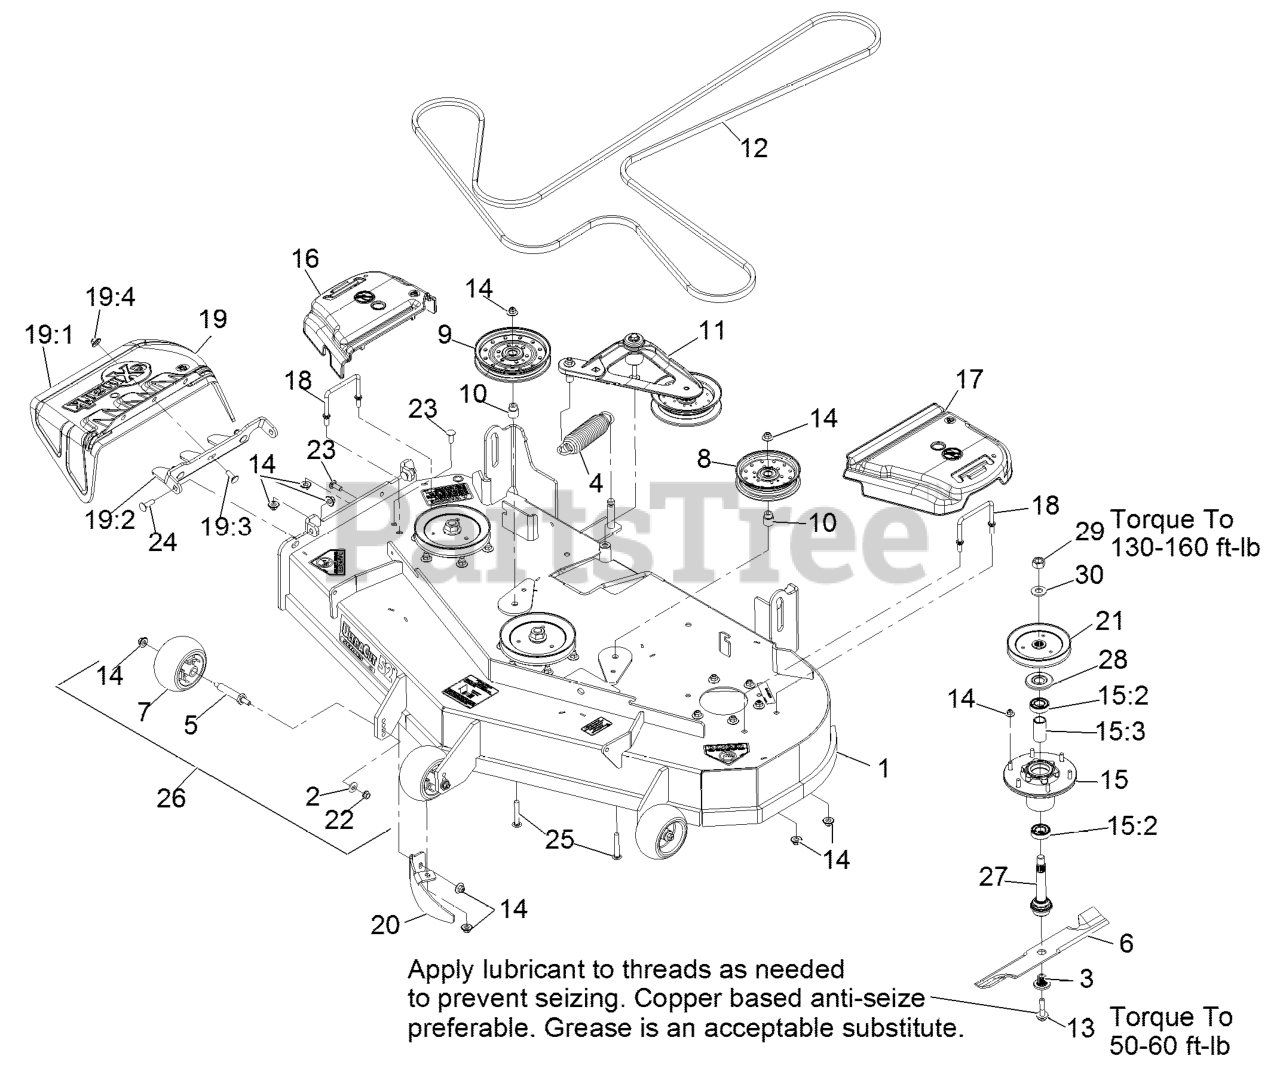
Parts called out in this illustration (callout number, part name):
1	ASM,524 DECK WITH DECALS
2	WASHER-BELLEVILLE
3	BUSHING,SPLINED
4	SPRING-EXTENSION
7	ROLLER-SCALP, ANTI
10	BUSHING-IDLER
11	DECK IDLER ASM
13	SCREW,SEMS 1/2-20 X 2.19
14	Nut-Nyloc 3/8-16 Flg
15	ASM-CUTTER HSG WITH BEARINGS
15:2	BEARING-BALL
15:3	SPACER-BEARING
16	COVER-BELT, RH
17	COVER-BELT, LH
18	WIREFORM-COVER
19	ASM,DISCHARGE CHUTE
19:1	CHUTE,DISCHARGE
19:2	BRACKET,DISCHARGE CHUTE
19:3	SCREW-CARR
19:4	Nut-Nyloc 3/8-16 Flg
20	BAFFLE-DOGLEG, LZE-PNS-52
21	SHEAVE,BLADE DRIVE 6.50
22	NUT-HHF, WHIZ
23	SCREW-CARR
24	Bolt-Carriage 3/8-16 X 1 1/4
25	SCREW-CARR
27	ASM-SPINDLE AND SEAL
28	GUARD,BEARING TOP .989
29	NUT-HEX
